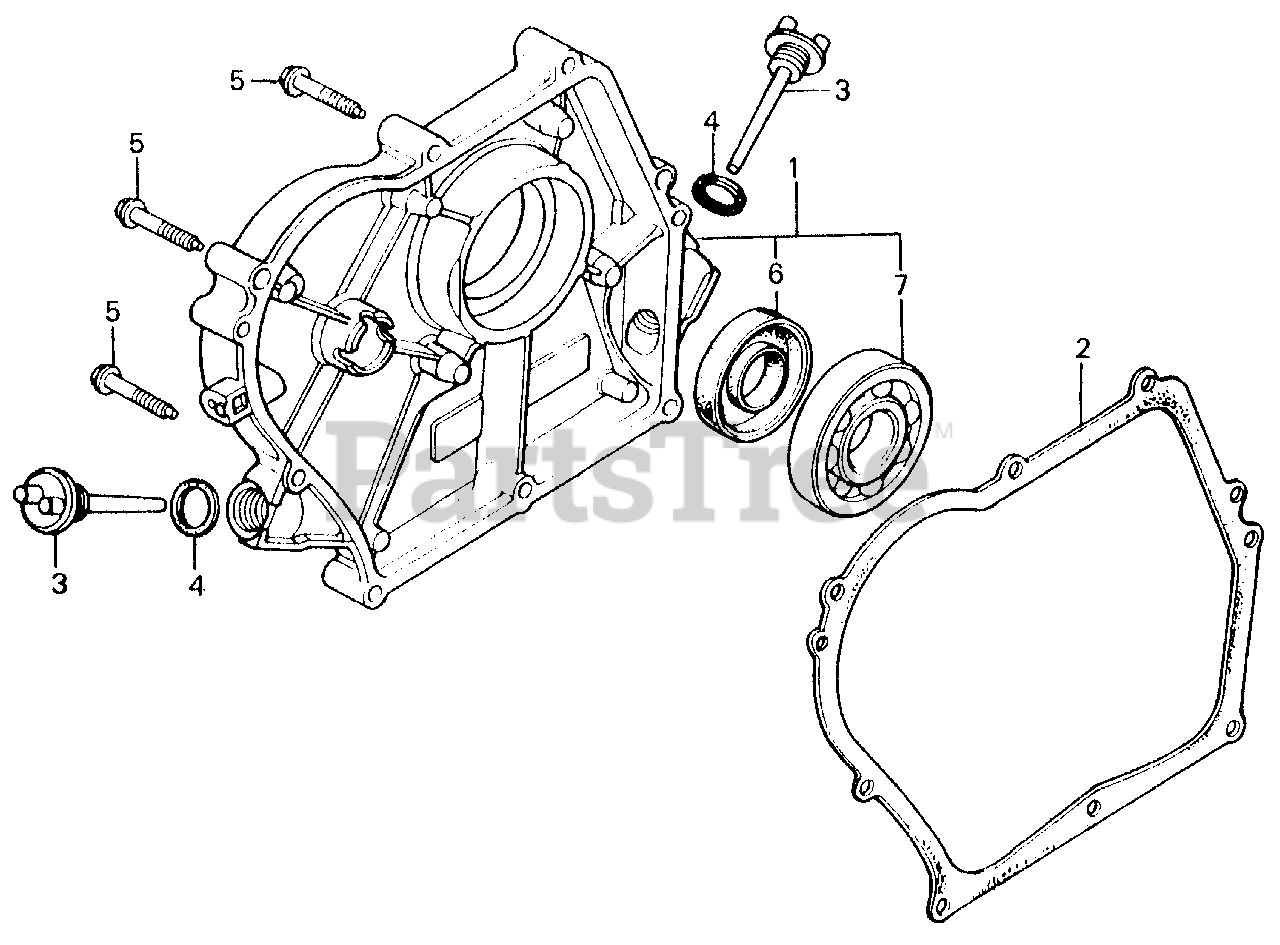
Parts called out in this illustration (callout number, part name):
1	COVER ASSY., CRANKCASE (S-TYPE)
1	COVER ASSY., CRANKCASE (HQ-TYPE)
2	GASKET, COVER
4	GASKET, OIL FILLER CAP
5	BOLT, FLANGE (6X32)
6	OIL SEAL (25X41X6)
7	BEARING, RADIAL BALL (6205)
